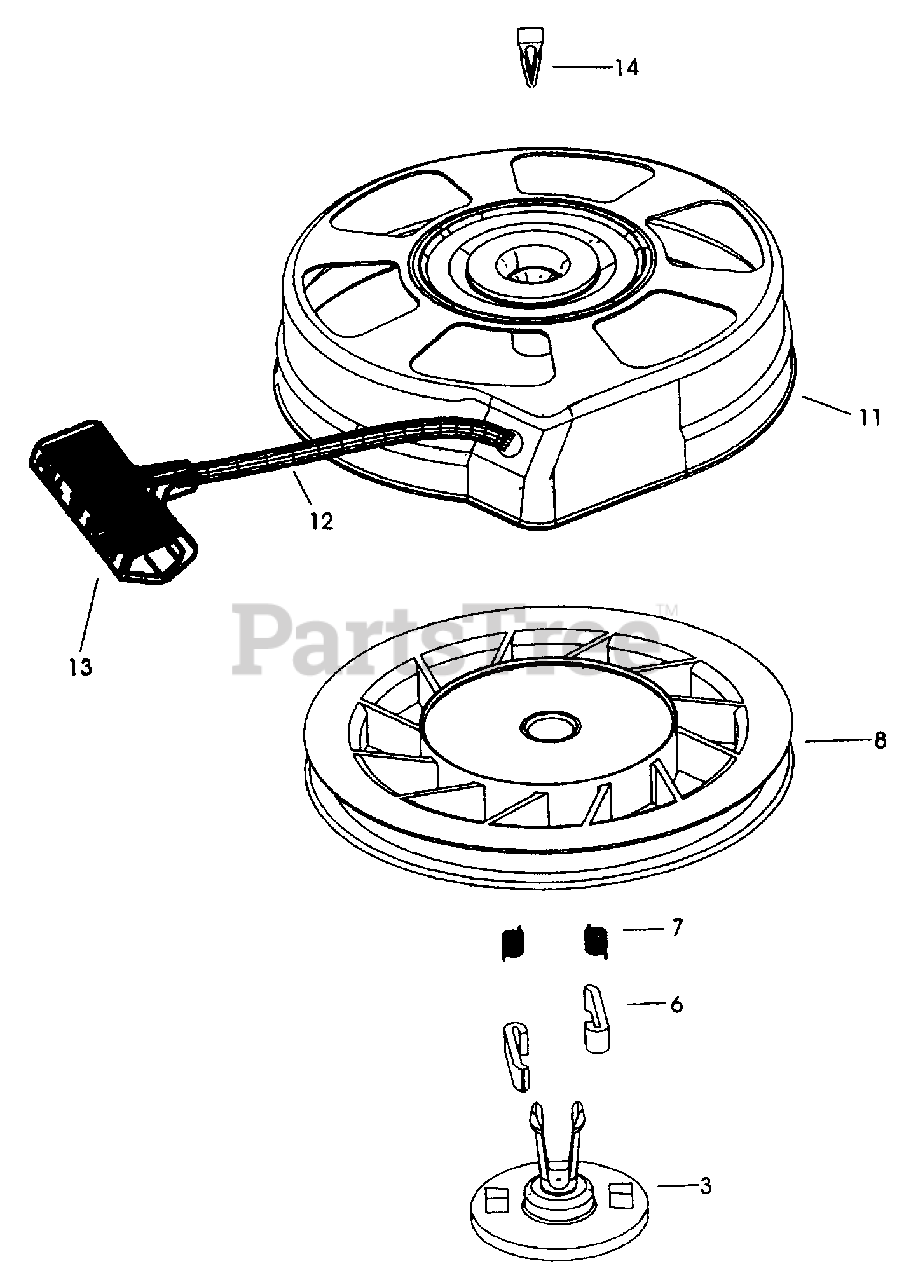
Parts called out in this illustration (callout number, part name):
3	Retainer
6	Starter Dog
7	Dog Spring
8	Pulley & Rewind Spring Ass'y
11	Starter Housing Ass'y (40 degree grommet)
12	Starter Rope (Length 98" x 9/64" dia.)
13	Starter Handle
14	Locking Tab
